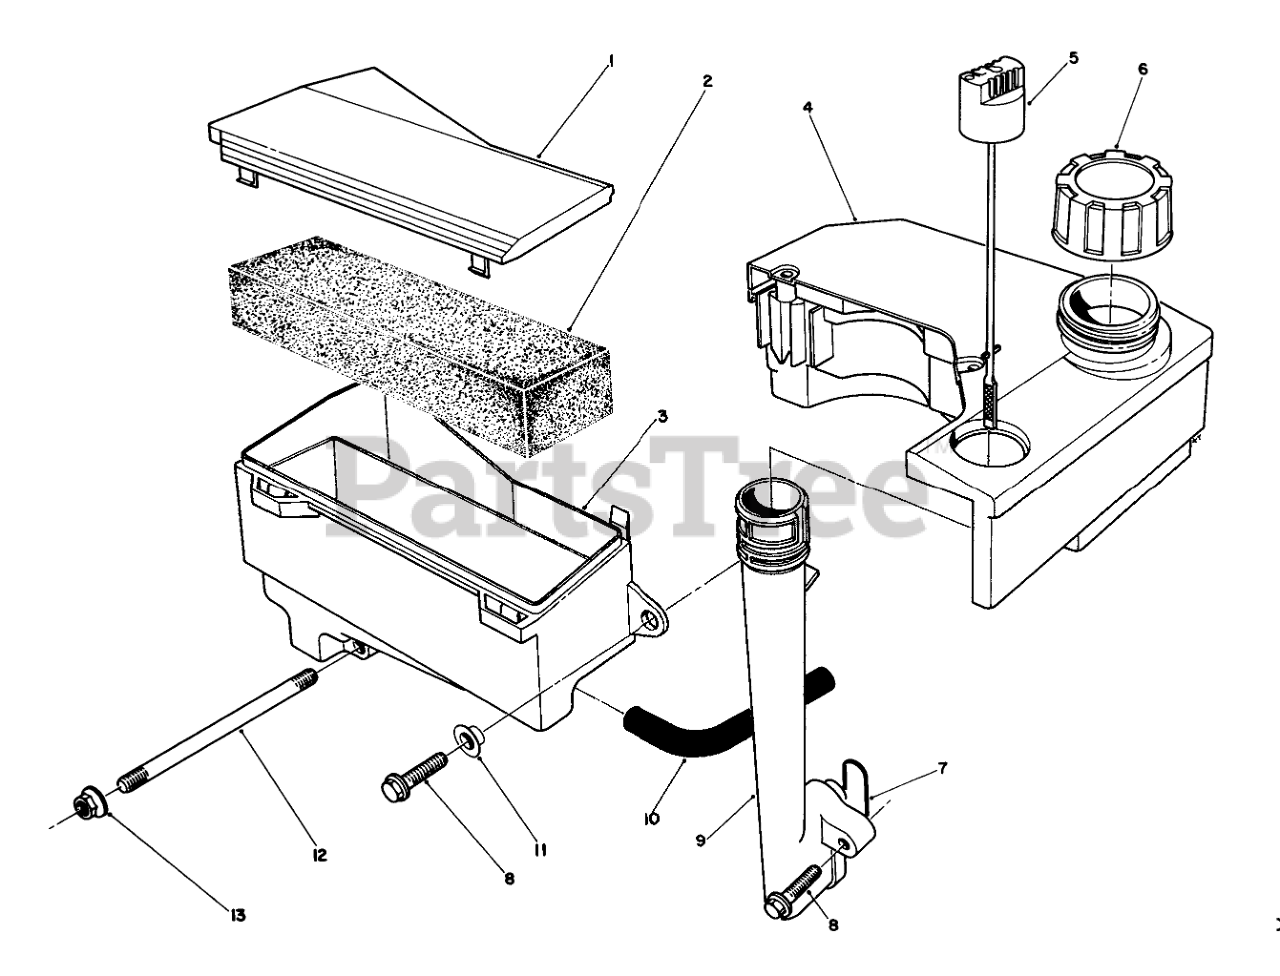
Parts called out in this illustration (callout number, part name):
1	AIR CLEANER CAP
3	Body-Air Cleaner
4	TANK ASM
5	Dipstick
6	GAS CAP ASM
7	O-RING
11	SPACER
12	Stud-Carburetor
